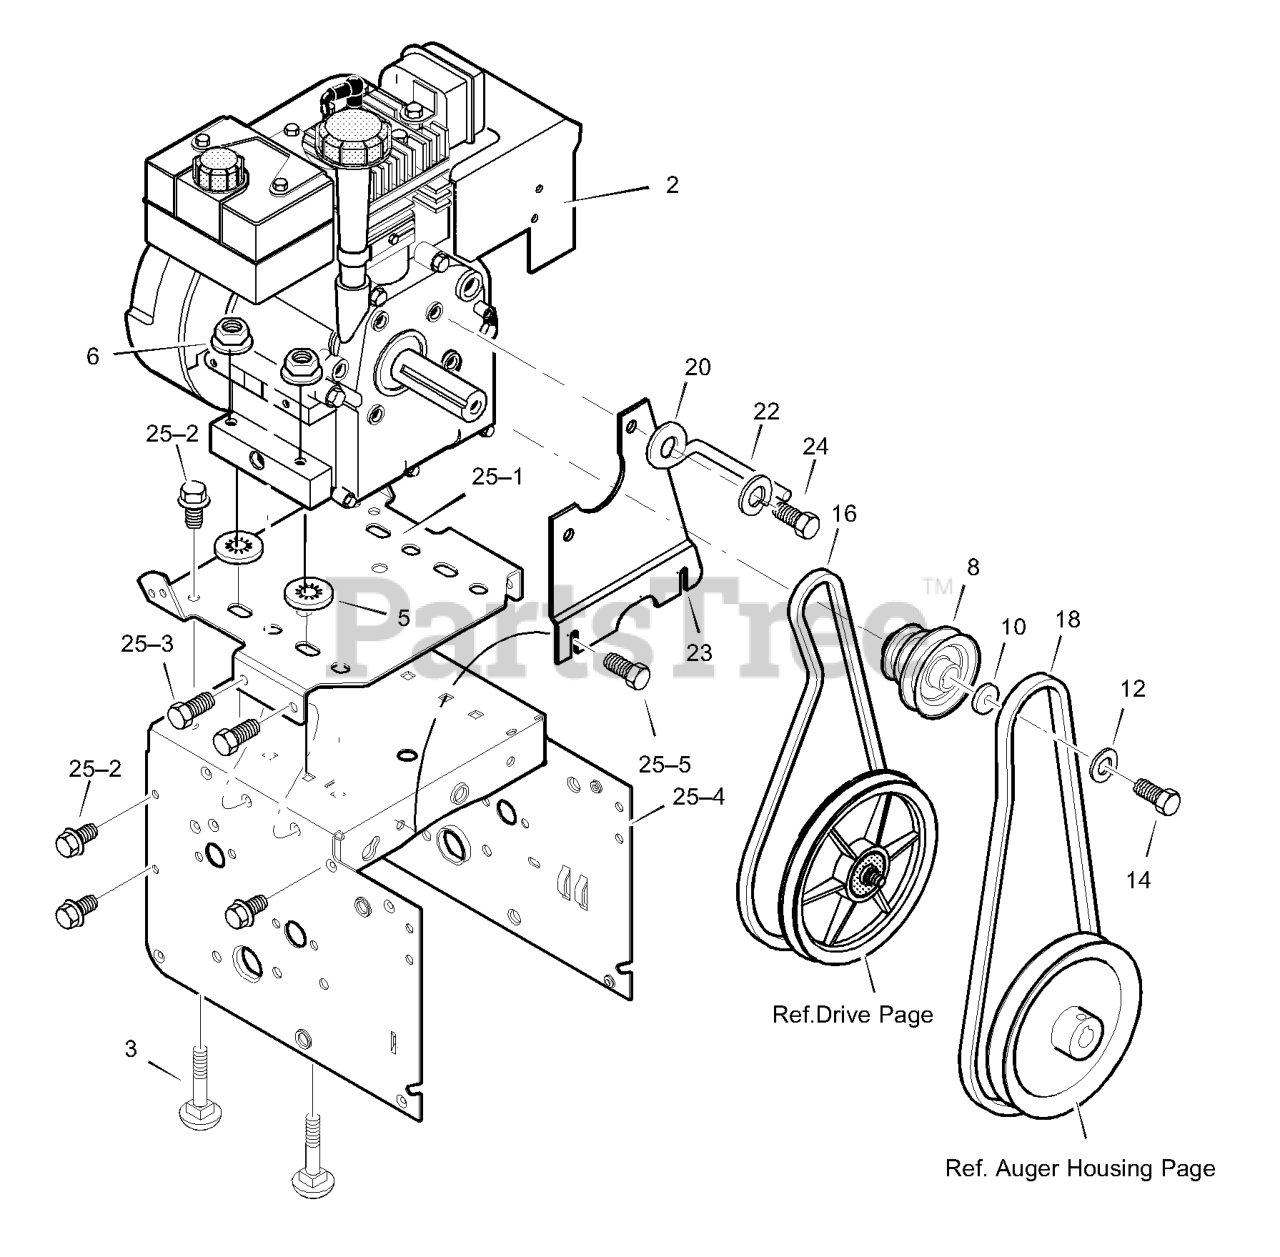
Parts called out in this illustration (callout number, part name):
2	ENGINE
3	BOLT, CARRIAGE 5/16-18
5	RETAINER, PUSH
6	NUT, HEX 5/16-18
8	PULLEY, ENGINE
10	WASHER
12	WASHER .38ID
14	SCREW, 3/8-24 x 1.00
16	BELT, V 3L 33.13LG
18	BELT, V 4L 38.1MF16" 5-10
20	GUIDE, BELT
22	WASHER, SPTLK .31X.58X.08
23	PLATE, ANTI VIBRATION
24	SCREW, 5/16-24 x 1.00
25	FRAME ASSEMBLY
25-1	PLATE, ENGINE MOUNT
25-2	SCREW, TAP 1/4-20 X .63
25-3	SCREW, TAP 5/16-18 X .50
25-4	FRAME, MOTOR BOX
